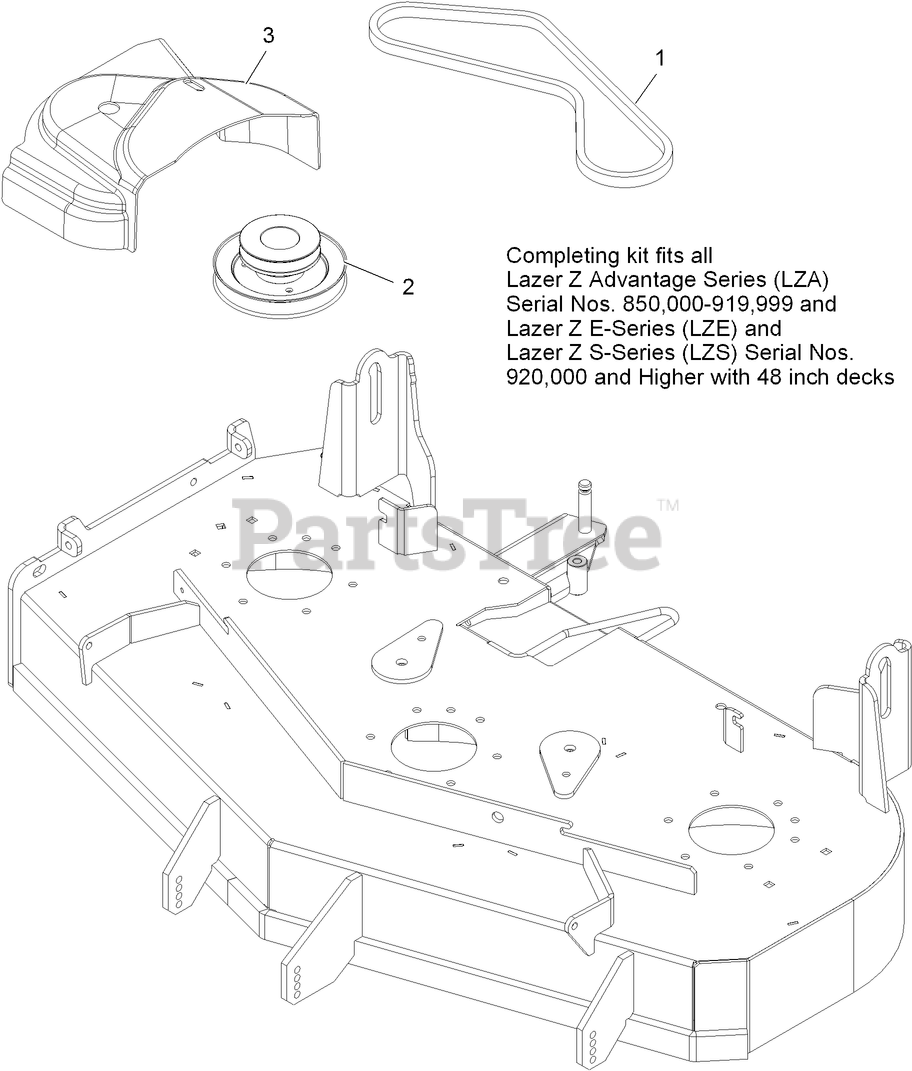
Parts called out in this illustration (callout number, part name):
1	BELT-BLOWER
2	JACKSHAFT-UV DRIVE, 484 SPLINED
3	COVER,BELT UV 48
